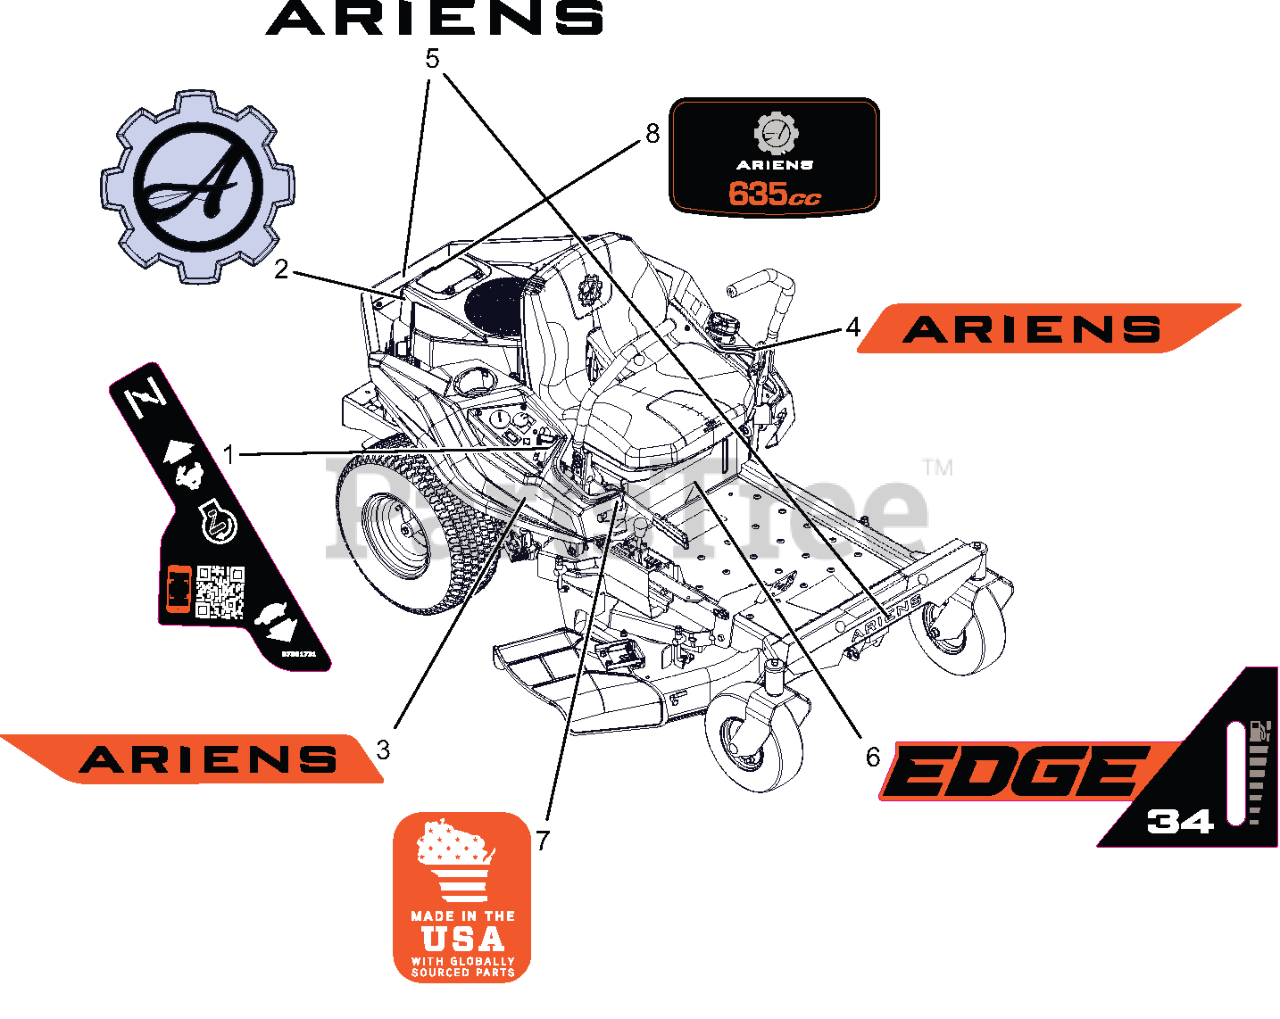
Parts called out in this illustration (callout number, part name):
1	DECAL- THROTTLE CONTROL EDGE
2	DECAL- ARIENS GEAR BADGE
3	DECAL- ARIENS (FENDER RH)
4	DECAL- ARIENS (FENDER LH)
5	DECAL- ARIENS 9.625" BLACK
6	DECAL- EDGE 34 KICKPLATE
7	DECAL- MADE IN USA
8	DECAL, ARIENS 653CC
